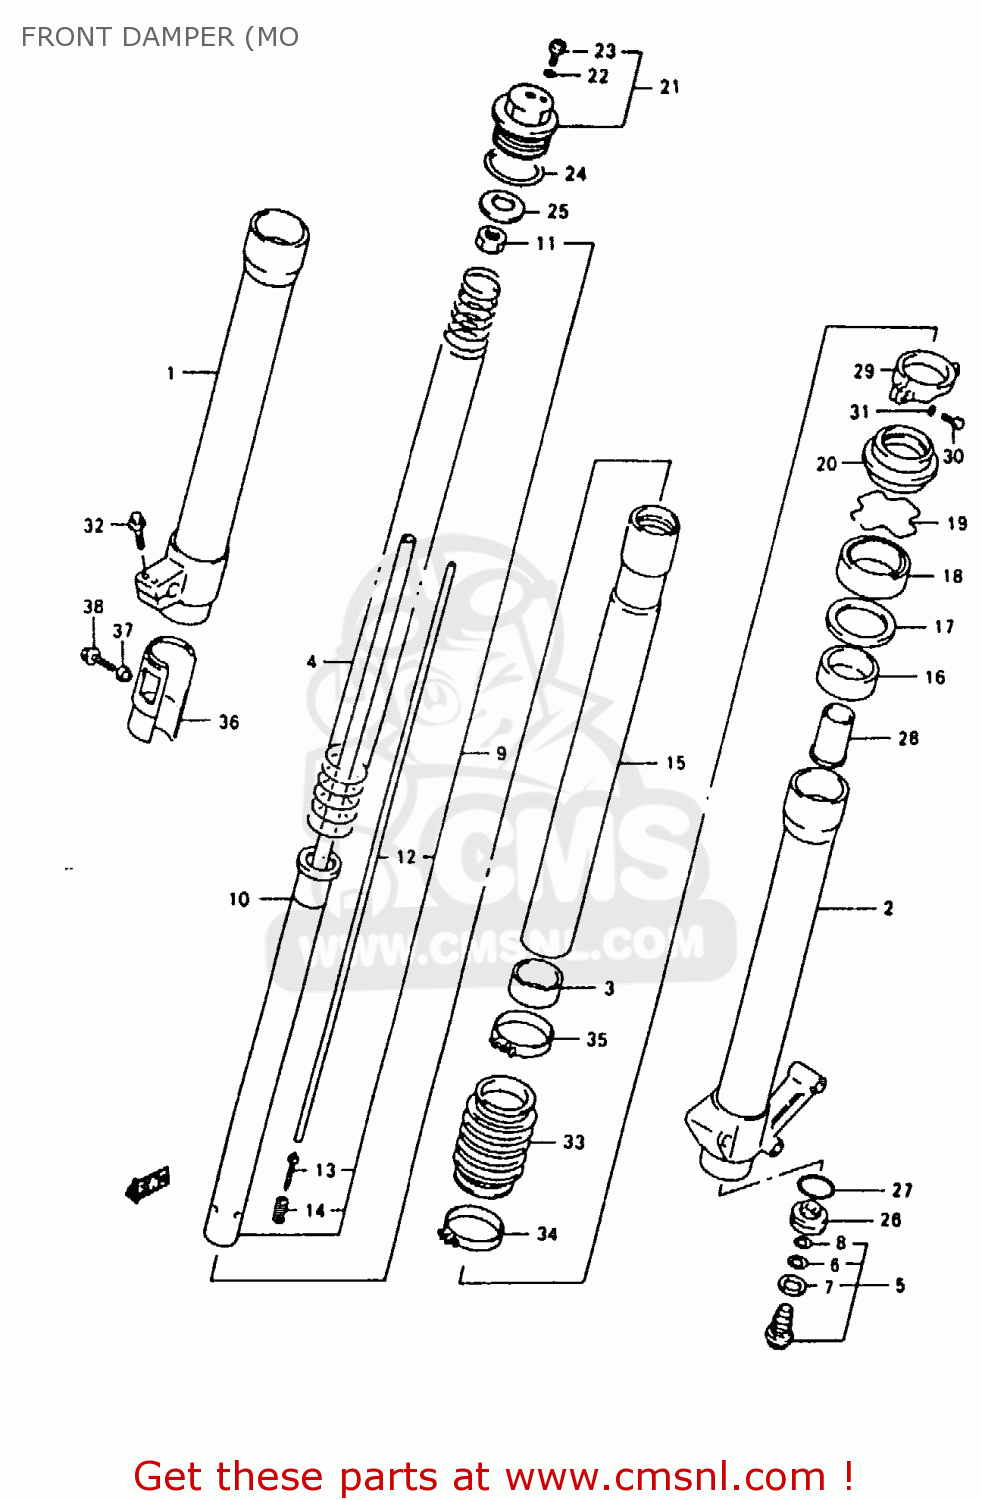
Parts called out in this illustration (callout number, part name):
1	TUBE,OUTER,RIGHT
2	TUBE,OUTER,LEFT
3	BUSH,SLIDE
4	SPRING,FR
5	BOLT,CTR
6	O RING,CTR BOLT
7	GASKET (NAS)
8	O RING,CTR BOLT UPR
9	DAMPER,FRONT
10	BUSH,SLIDE
11	NUT, PUSH
12	ROD,PUSH
13	NEEDLE
14	SPRING,PUSH ROD
15	TUBE,INNER
16	BUSH,GUIDE
17	SPACER,SEAL
18	SEAL,OIL
19	RING,OIL SEAL STOPPER
20	SEAL,DUST
21	BOLT,FORK
22	O RING,PLUG
23	BOLT,PLUG
24	O RING
25	JOINT,SPRING
26	PLATE,END
27	O RING
28	PIECE,OIL LOCK
29	HOLDER
30	BOLT
31	WASHER (5.3X10X1.0)
32	BOLT
33	BOOT
34	CLAMP
35	BAND,BOOT
36	PROTECTOR,OUTER TUBE,RIGHT
37	WASHER
38	BOLT
